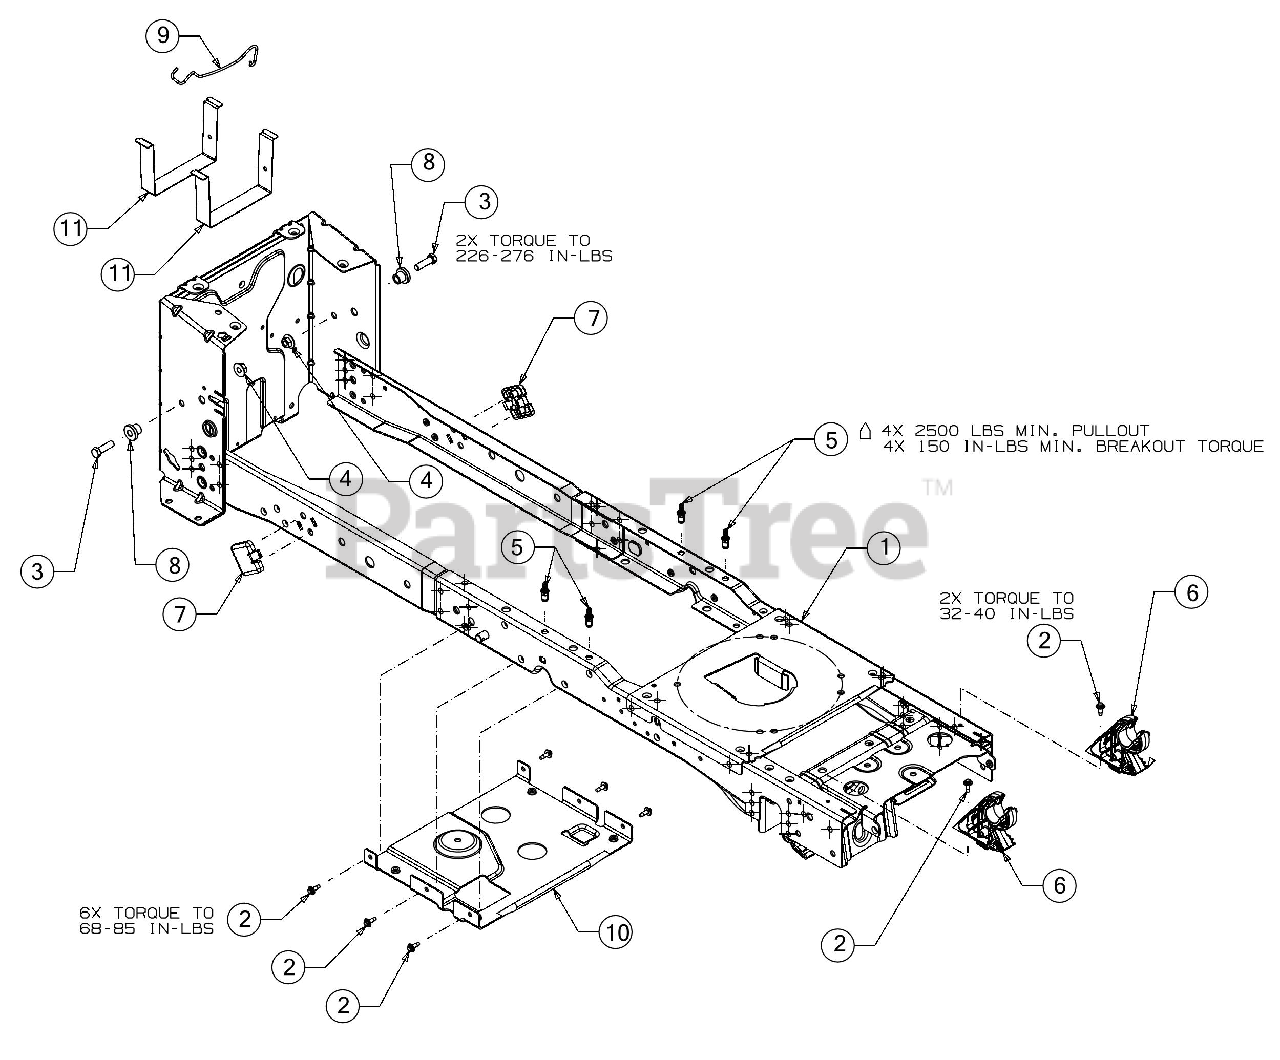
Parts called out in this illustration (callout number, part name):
1	FRAME ASSEMBLY
2	SCREW M6-1 X .625
3	SCREW 3/8-16 X 1.25 GR5
4	FLANGE LOCK NUT
5	RIVET-HEX STUD 1/4-20 FRM
6	HOOD PIVOT BRACKET
7	LIFT ROD WEAR PAD
8	SHOULDER SPACER
10	FRAME BRACE BRACKET
11	BATTERY BRACKET
